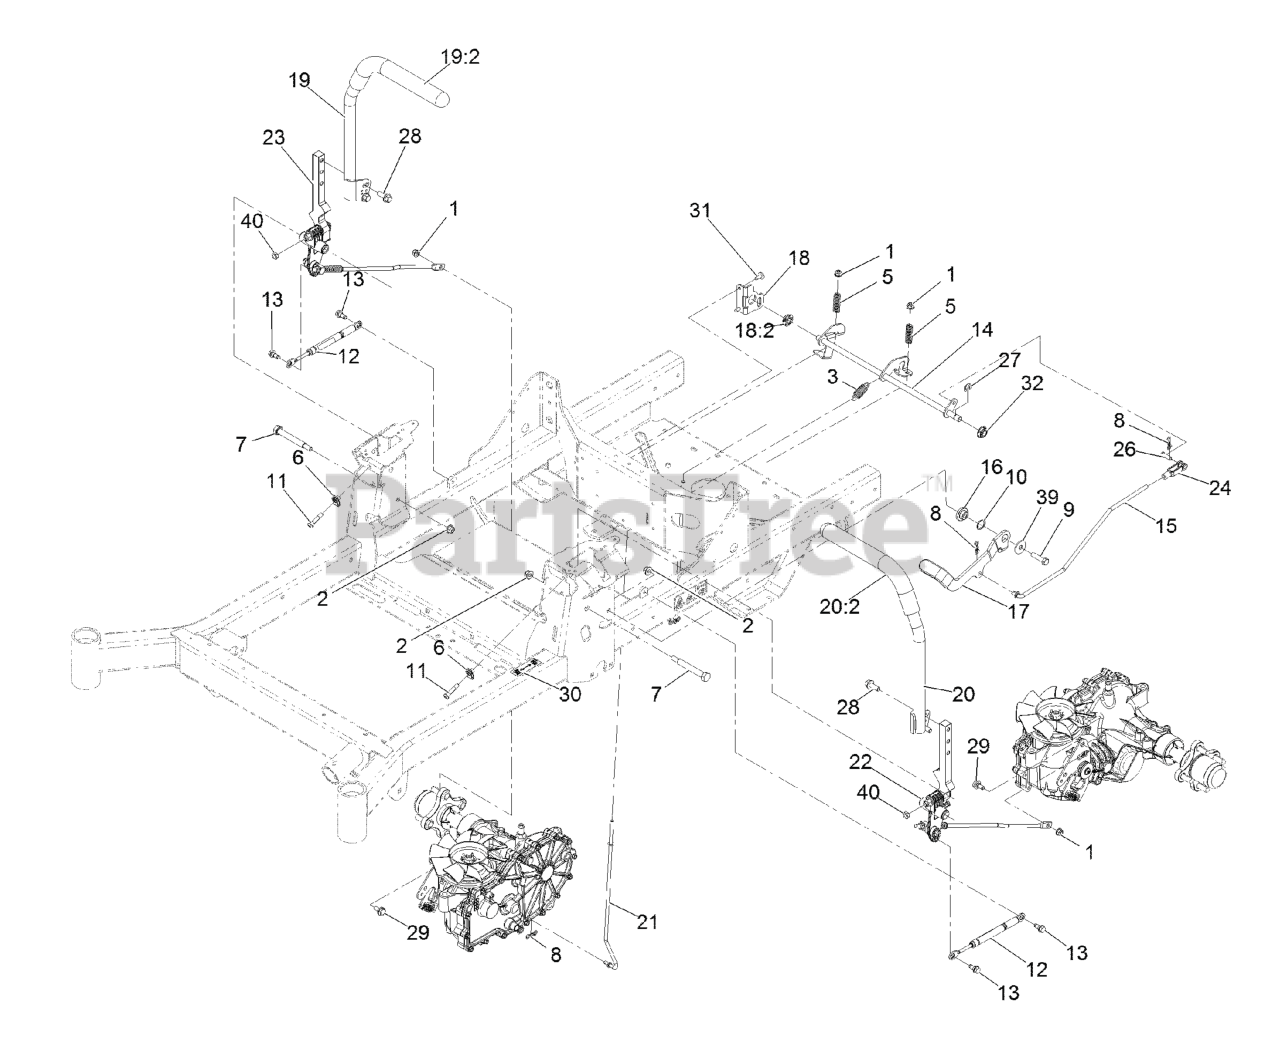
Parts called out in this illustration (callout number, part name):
1	NUT-HF, NI
2	NUT-HF, NI
3	SPRING-EXTENSION
5	SPRING-COMPRESSION
7	BOLT-PIVOT
8	PIN-COTTER, LOCKING
9	SCREW-HH
10	WASHER-WAVE
11	SCREW-HSBH
13	SCREW-SHOULDER
14	SHAFT-BRAKE
15	LINKAGE-BRAKE, UPPER
16	PIVOT-FLANGE
17	LEVER-BRAKE (WITH GRIP)
18	BRACKET-BRAKE
18:2	BEARING-SPHERICAL
19	RH EXTENDED CONTROL HANDL
20	LH EXTENDED CONTROL HANDL
21	LINKAGE-BRAKE, LOWER
22	LH Motion Control ASM
23	RH Motion Control ASM
24	YOKE-ADJUSTABLE
26	PIN-CLEVIS
27	RING-RETAINING, EXTERNAL
28	SCREW-HHF 3/8-16 X 1
29	BOLT-SHOULDER,HFH
30	DECAL-BRAKE, PARKING
31	SCREW-TORX
32	BEARING-SPHERICAL
39	WASHER
40	NUT-JAM
